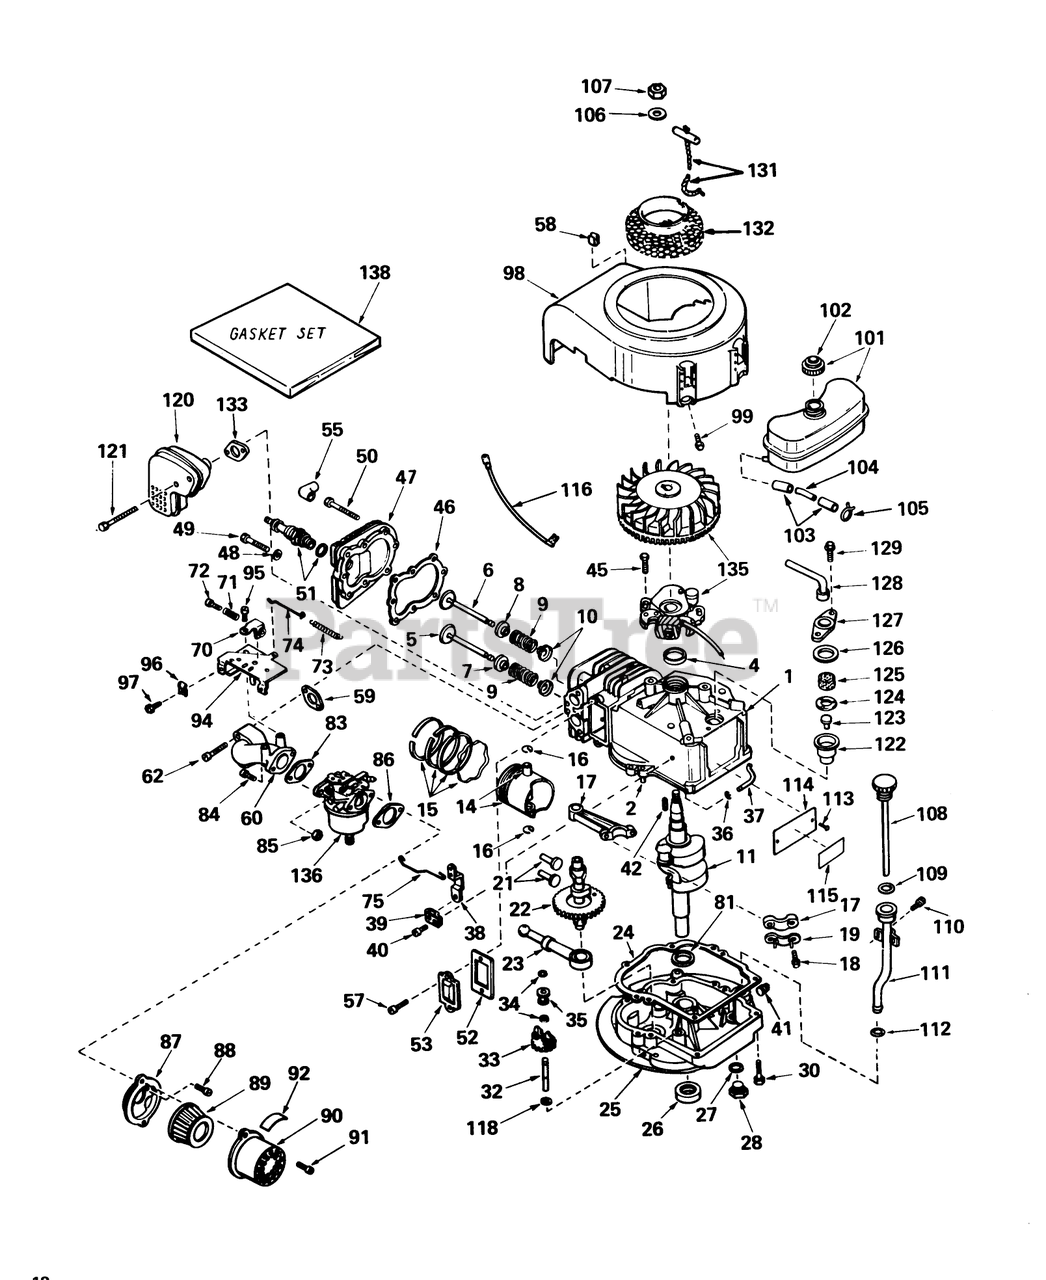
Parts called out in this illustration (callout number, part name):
1	Cylinder Assy. (Incl. Nos. 2 4)
2	Pin-Dowel
4	Seal-Oil
5	Valve, Intake (Standard) (Incl. Nos. 7, 9 10)
5	Valve, Intake (1/32" Oversize) (Incl. Nos. 7, 9 10)
6	Valve, Exhaust (Standard) (Incl. Nos. 8, 9 10)
6	Valve, Exhaust (1/32" Oversize) (Incl. Nos. 8, 9 10)
7	Cap-Upper Valve Spring
8	Cap, Upper Valve Spg (Exhaust)
9	Spring-Valve
10	Cap-Valve, Spring
11	Crankshaft Assy.
14	Piston Pin Assy. (Standard) (Incl. 2 of No. 16)
14	Piston Pin Assy. (.010 Oversize) (Incl. 2 of No. 16)
14	Piston Pin Assy. (.020 Oversize) (Incl. 2 of No. 16)
15	Ring Set-Piston Std.
15	Ring Set-Piston .010 oversize
15	Ring Set-Piston .020 oversize
16	Ring-Retaining, Piston Pin
17	Rod Assy., Connecting (Incl. Nos. 18 19)
18	Connecting Rod Bolt
19	Plate Lock
21	Lifter-Valve
22	Camshaft (Compr. Release)
23	Oil Pump ASM
24	Gasket, Mounting
25	Flange Assy., Mounting (Incl. Nos. 26, 27, 28 32)
26	Seal-Oil
27	Gasket-Oil Drain
28	Plug, Drain
30	Screw (1/4-20 x 1-1/4)
32	Shaft-Governor
33	Governor Gear ASM
34	Ring-Retaining
35	Spool-Governor
36	Washer-Flat
37	Rod, Governor (Incl. No. 36)
38	Governor Lever
39	Clamp-Lever, Governor
40	Screw
41	Plug-Pipe
42	Key Flywheel
45	Screw
46	Oil Fill Tube
47	Head Cylinder
48	Washer
49	Screw
50	Screw Hex Hd. Cap
51	Plug, Spark (J17LM or equiv.)
52	Gasket-Breather
53	Cover-Valve
55	Cover-Spark Plug
57	Screw
58	51004 GIL ROTARY TI
59	Gasket, Intake
60	Pipe, Intake
62	Screw, Fil. Slotted Hd.Sems
70	Brachet, Control
71	Spring
72	Screw, Hex Hd.
73	Spring, Governor
74	Link Governor Spring
75	Link Governor
81	Washer-Thrust
83	Gasket
85	Nut and Lock Washer (1/4-28)
86	Gasket
87	Bracket
88	Screw (10-32 x 1/2)
89	Element
90	Body
91	Screw
92	Decal
94	Control Assy., Speed
95	Screw (10-24 x 9/16)
96	Conduit
97	Screw (10-32 x 3/8)
98	61718/GIL1605A/95-5
99	Screw (1/4-20x19/32)
101	Tank Assy., Fuel (Incl. No. 102)
102	Cap, Fuel
103	Line-Fuel (8.62)
104	Line, Fuel
105	Clamp-Line, Fuel
106	Washer-Spring
107	Hex Nut
108	Dipstick, Assy., Oil (Incl. No.109)
109	O-Ring
110	Screw (10-32 x 1/2)
111	Tube Assy., Oil Fill
112	O-Ring
113	Stud
114	IDENTIFICATION PLATE
115	480B GIL SNWTHWR O/
116	SPOOL RETAINER (10-PK)
118	Washer-Flat
120	Muffler
121	Screw-Fil. Hd.
122	Body Breather Tube
123	Valve Check
124	2000A37 WIZARD ROTA
125	Element-Breather
126	Gasket-Breather
127	Cover Breather
128	Tube, Breather
129	Screw, Hex Hd. w/Conical
131	Rope Assy., Starter
132	61719/GIL1607A,VARI
133	Gasket-Exhaust
135	Magneto
136	Carburetor
138	Gasket Set
